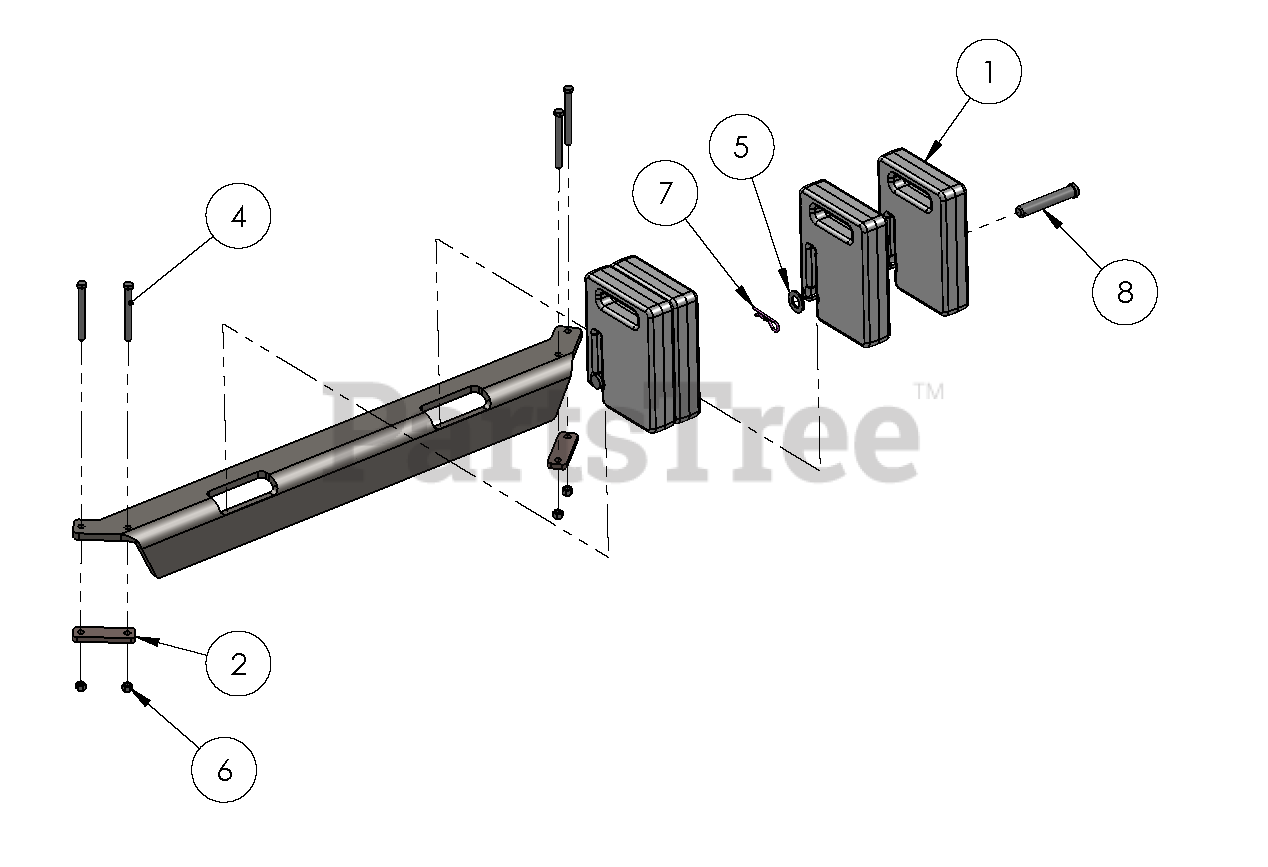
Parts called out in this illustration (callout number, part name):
1	WEIGHT-CAST 28LB FRONT
2	PLATE, FRONT WEIGHT FRAME
3	BRACKET, FRONT WT FM 4-WTS
4	@BLT-HEX .38-16X4.00 GR5 YWZC
5	@WSHR-FL-STL.812X1.50X.135YWZC
6	NUT-LK-CROWN, 3/8-16 GR 5 YWZC
7	HAIR PIN COTTER .125 44718
8	PIN-CLEV .75X4.50 YWZC
